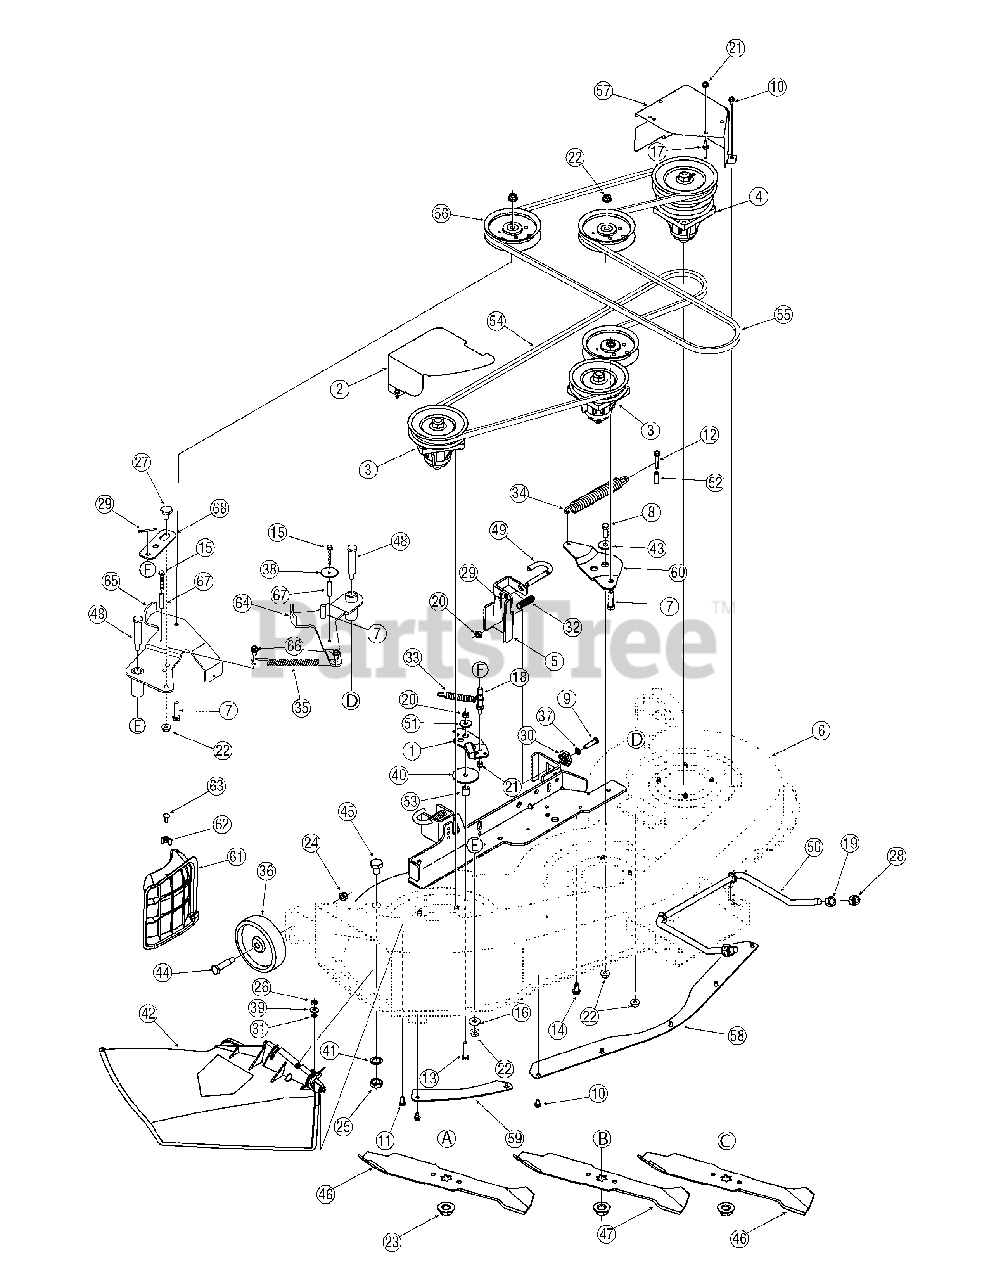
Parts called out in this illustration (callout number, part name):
1	Brake Assembly, Deck
3	Spindle Assembly, 5.00 Dia.
4	Spindle Ass’y, Double Pulley
7	Screw, 3/8-16, 1.50, Gr5
8	Screw, 3/8-16, 1.00, Gr5
9	Screw, 5/16-18, 1.25, Gr5
10	Screw, 1/4-20, 0.500
11	Screw, 1/4-20, .75, Gr5
12	Screw, 1/4-20, 1.500
13	Screw, 5/16-18, 1.50, Gr5
14	Screw, Ld, 5/16-18, 0.750
15	Screw, 1/4-20 x 1.75
16	Washer, Flat, .406 x 1.25 x .157
17	Belt Guard Pin 1/4 Dia x 1.43
18	Pin, 1/4-20, 3/8 x 2.0
19	Nut, Hex, 1/2-13, Gr5
20	Nut, Flange Lock, 5/16-18, GrF
21	Nut, Flange Lock, 1/4-20, GrF
22	Nut, Flange Lock, 3/8-16, GrF
23	Nut, Flange, 5/8-18
24	Nut, Flange Lock, 3/8-16, GrF
25	Nut, Hex, M16-1.5
26	Nut, Hex, 1/4-20, Gr5
27	Shld, Screw, .625 Dia. x .217
28	Nut, Hex Lock, 1/2-13, Gr8, Nylon
29	Pin, Cot, 1/8 x 1.25
30	Adjustment Gear, Deck
31	Nut, Push, .25 ID x .50 OD
32	Sprg, Compress, .531 OD x 1.75
33	Spring, Extension, .50 Dia x 3.97
34	Spring, Extension, .91 Dia x 7.33
35	Spring, Extension, .75 OD
36	Wheel, Deck 5.0 x 1.38
37	Washer, Lock, 5/16
38	Washer, Flat, .285 x 1.25
39	Washer, Bell, .265 x.75 x .062
40	Washer, Flat, .34 x 2.25 x .10
41	Washer, Lock, 5/8
42	Chute Assembly
43	Spacer, Shoulder, .625 ID x .169
44	Spacer, Shoulder, .498 x 1.53
46	Blade, 16.28", Star 3-in-One
47	Blade, 14.88", Star 3-in-One
48	Shld. Screw, .625 x 2.515
49	Rod, Deck Release
50	Rod, Deck Adjustment
51	Shoulder Spacer
52	Spacer, .260 x .372 x 1.030
53	Spacer, .375 x .63 x .595
54	Belt, V-Type, Poly, A x 79.0 LG
55	Belt, V-Type, A x 90.24
56	Pulley, Idler, 4.25" Dia.
59	Deck Skirt, RH
60	Bracket, Idler
61	Mulch Plug (if equipped)
62	Wing Nut (if equipped)
63	Carriage Screw, 1/4-20 x .62 (if equipped)
67	Spacer, .260 x .372 x 1.420 LG
17258E-0606	COVER:BELT:DECK 46 - MAJESTIC ORANGE (0606)
17258E-0637	Deck Belt Cover, 46" Black - POWDER BLACK (0637)
17258E-0650	COVER:BELT:DECK 46 - RED METALLIC (0650)
17258E-0665	COVER:BELT:DECK 46 - YARDMAN GREEN (0665)
17258E-0691	COVER:BELT:DECK 46 - BLACK JACK (0691)
17258E-4008	COVER:BELT:DECK 46 - WINE RED (4008)
